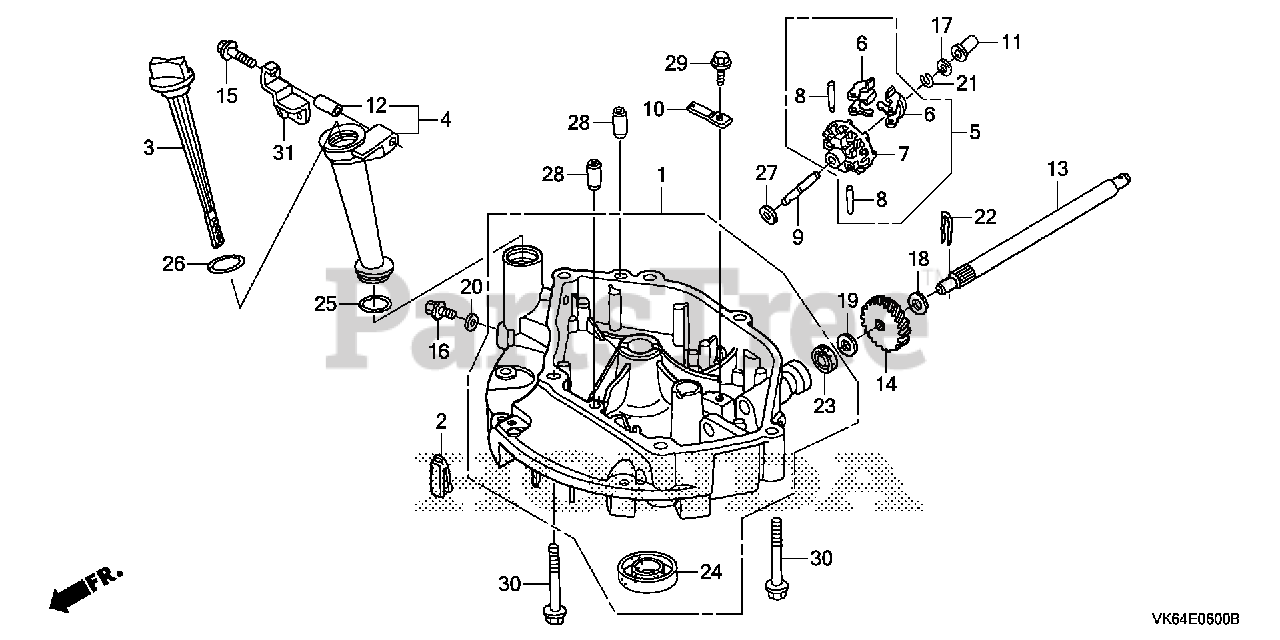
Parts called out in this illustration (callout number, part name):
1	PAN ASSY., OIL
2	RUBBER, OIL RETURN
3	GAUGE, OIL LEVEL Use up to Engine SN 1257294.
4	EXTENSION, OIL FILLER (106MM)
5	GOVERNOR ASSY.
6	WEIGHT, GOVERNOR
7	HOLDER, GOVERNOR WEIGHT
8	PIN, GOVERNOR WEIGHT
9	SHAFT, GOVERNOR HOLDER
10	PLATE, GOVERNOR SHAFT HOLDER
11	SLIDER, GOVERNOR
12	COLLAR, EXTENSION Use up to Engine SN 1257294.
13	SHAFT, DRIVE
14	GEAR, DRIVEN (18T)
15	BOLT, FLANGE (6X32)
16	BOLT, DRAIN PLUG
17	WASHER, THRUST (6MM)
18	WASHER, THRUST (12MM)
19	WASHER (10X21)
20	WASHER, DRAIN PLUG (10.2MM)
21	CLIP, GOVERNOR HOLDER
22	PIN, LOCK (2.0)
23	OIL SEAL (12X20X6.5) (NOK)
23	OIL SEAL (12X20X6.5)
24	OIL SEAL (25.4X40X7)
25	O-RING (22.1X2.2)
26	O-RING (25.5X3)
27	WASHER, PLAIN (6MM)
28	PIN A, DOWEL (8X14)
29	BOLT, FLANGE (6X12) Use from Engine SN 2086984.
30	BOLT, FLANGE (8X50)
31	HOLDER, CABLE
